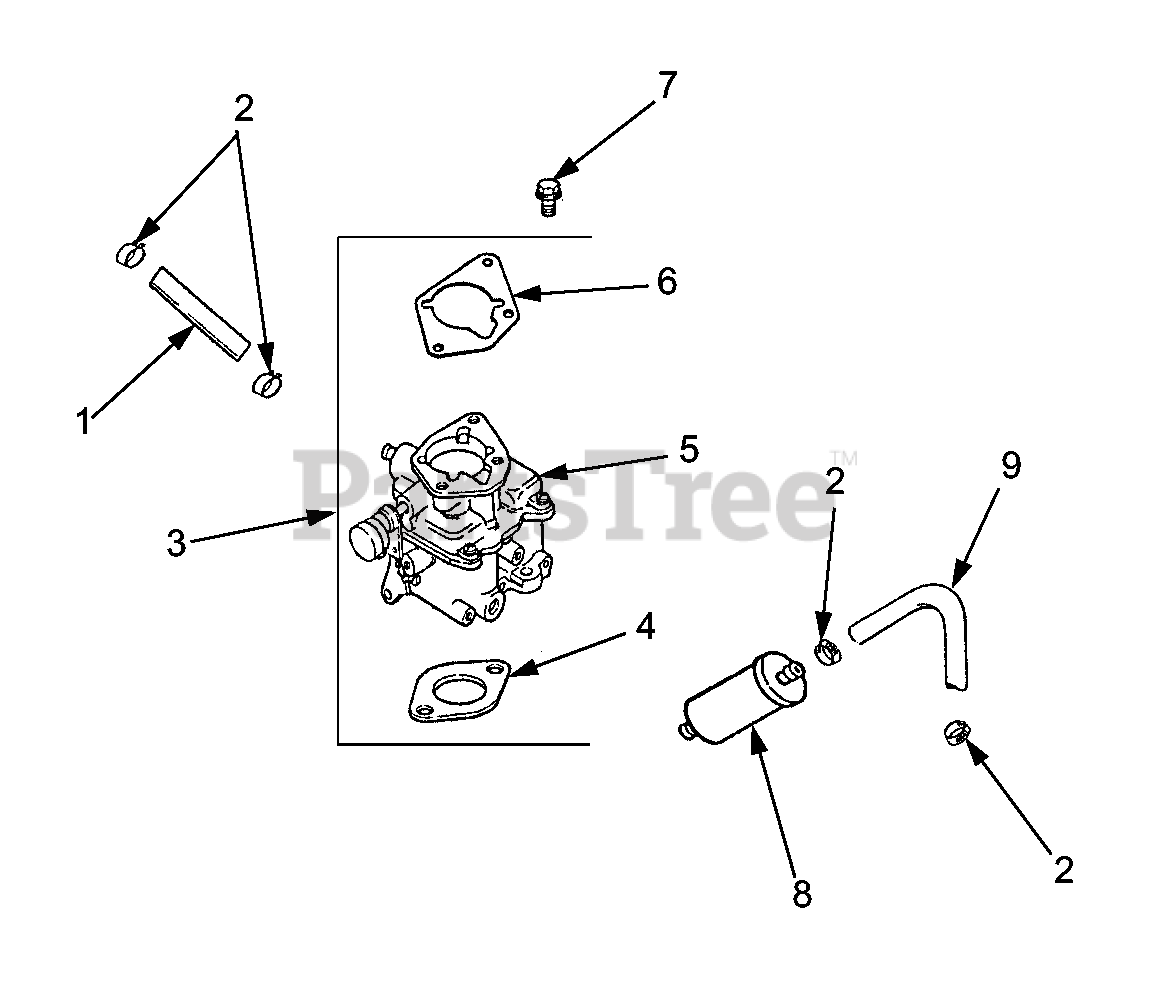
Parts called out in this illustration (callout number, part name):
1	Line, Fuel 10"
2	Clamp, Hose
3	Kit, Carburetor w/Gasket
4	Gasket, Carburetor
5	Carburetor Assembly
6	Gasket, Air Cleaner Base
7	Screw, Hex Flange
8	Filter, Fuel
9	Line, Fuel 11"
